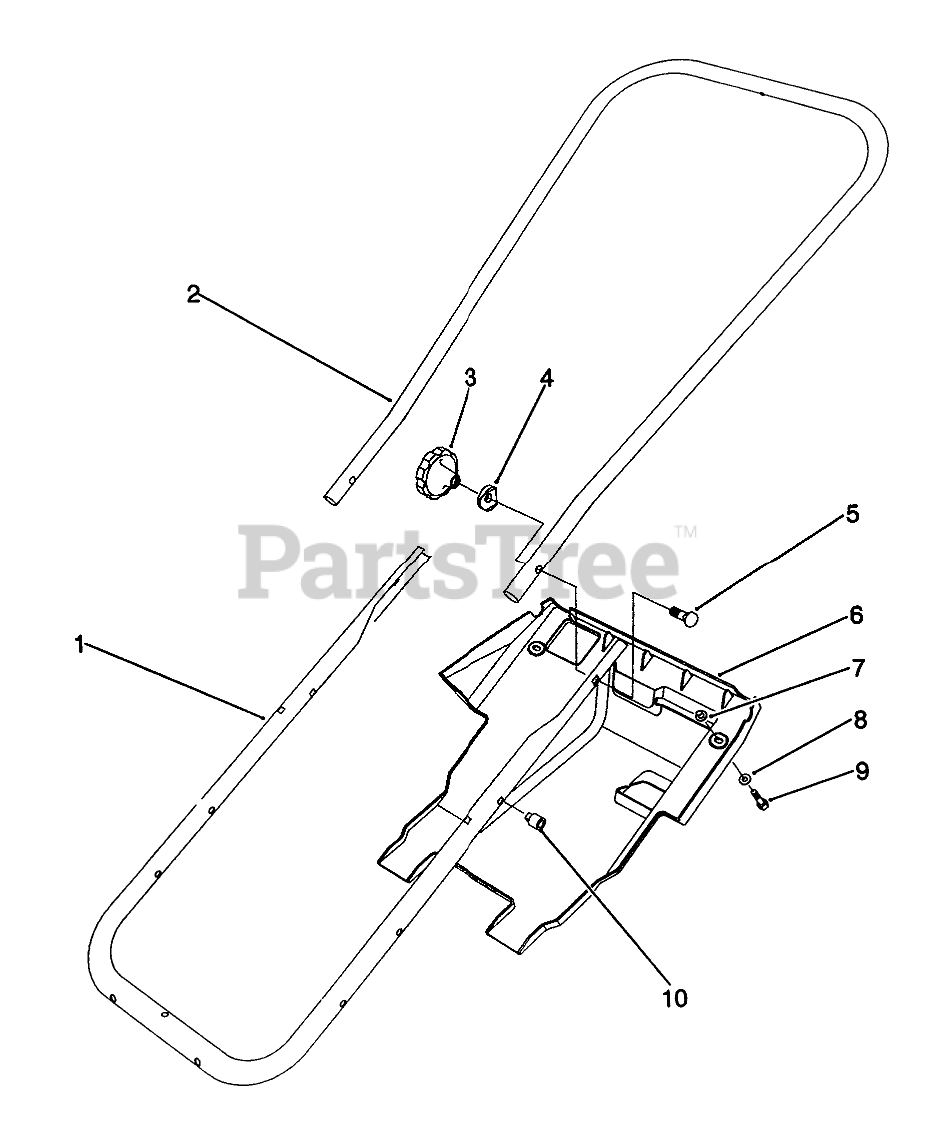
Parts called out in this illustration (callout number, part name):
1	Tube-Frame
2	Handle-Upper
4	WASHER-CURVED
5	SCREW-HANDLE
6	SHROUD
7	Nut-Push
8	WASHER-FLAT
9	SCREW-HWHTF
10	NUT-EXPANSION
